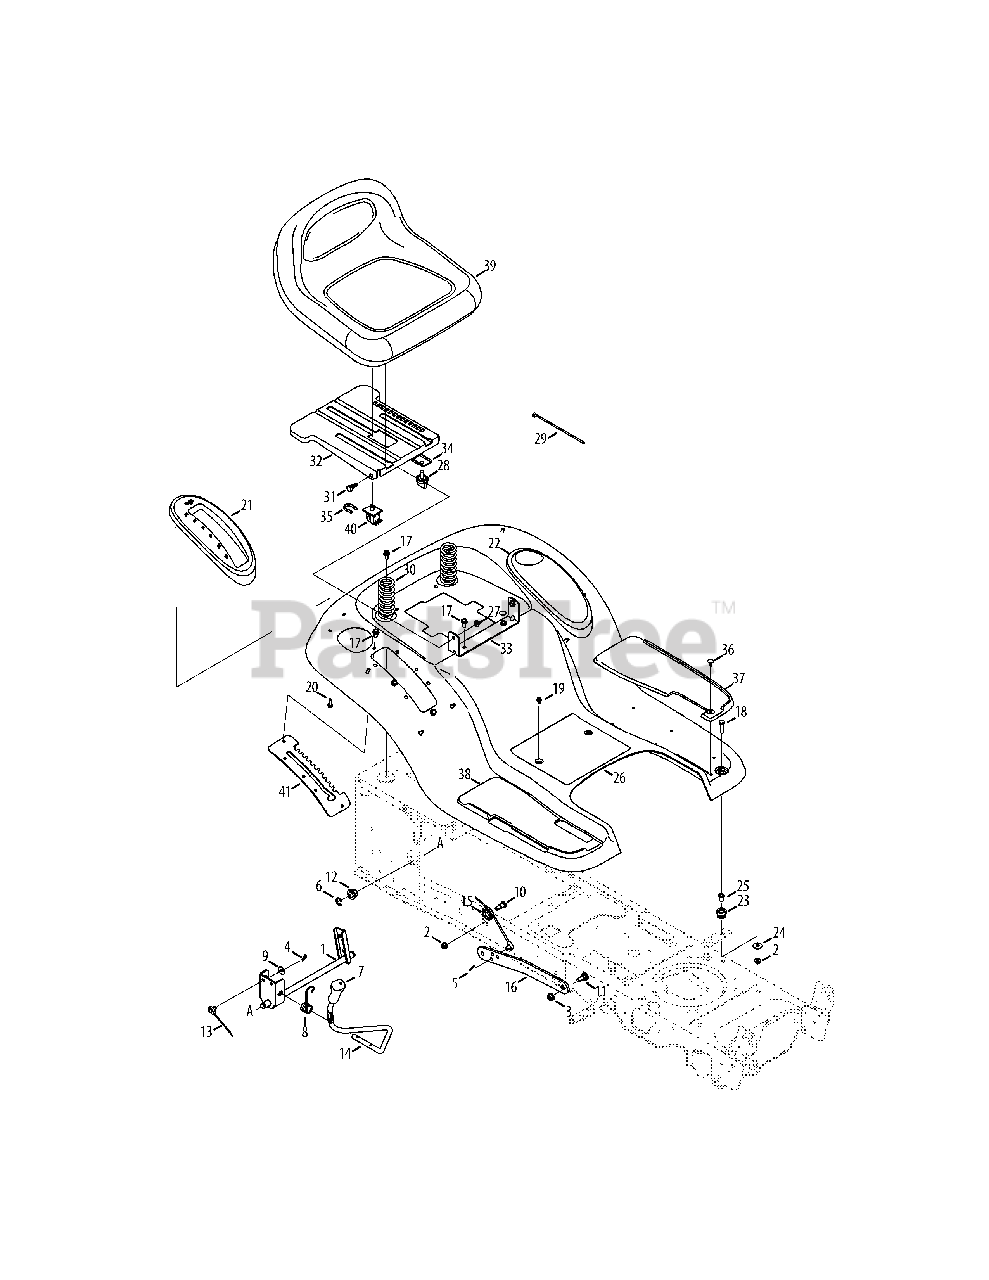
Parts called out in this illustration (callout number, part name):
1	Shaft Ass’y, Lift
2	Nut, Flange Lock, 5/16-18, Grf
3	Nut, Flange Lock, 3/8-16, Grf
4	Pin, Cotter, .072 Dia. x 1.13
5	Pin, Cotter, Bow-Tie 72
6	Ring, E Type, .625 Dia. Shaft
7	Grip, Handle, 1/2
8	Spring, Torsion
9	Washer, Spring, .401 x .870 x .063
10	Screw, Shoulder, .437 x .470, 5/16-18
11	Bolt, Shoulder, .500, 3/8-16
12	Bearing, Hex Flange
13	Cable, Lift, 16.16
14	Handle, Lift,
15	Pulley, Roller, Cable
17	Screw, Self-tapping, 5/16-18, .750,
18	Hex Screw, 5/16-18, 1.25, Gr5, Std
19	Screw, Self-tapping, 1/4-20, 0.500,
20	Screw, HL, 1/4-15, 0.750,
21	Cover, Lift Lever
22	Cover w/ Cup Holder
23	Grommet, .4375 ID x .750
24	Washer, Flat .344 x 1.00 x .063
25	Spacer, Flange, .3125 x .4375 x .625
27	Nut, Flange Lock, 5/16-18, Gr5, Sd Lk
28	Knob, 3/8-16, .875
29	Cable, Tie, 3/16 x .05 x 7.4
30	Spring, Comprs, 1.50 x 3.90 x .200
31	Screw, Shoulder, .437 x .268, 5/16-18
32	Bracket, Mounting, Seat
33	Bracket, Pivot, Seat
34	Bracket, Knob Adjustment, Seat
35	Clip, Retaining, Switch
36	Clip, Ratchet, .250 Dia
37	Pad, Foot, LH
38	Pad, Foot, RH
39	Seat, Medium Back
40	Switch, Seat
41	Bracket, Lift, Man PTO, 6 Pos
